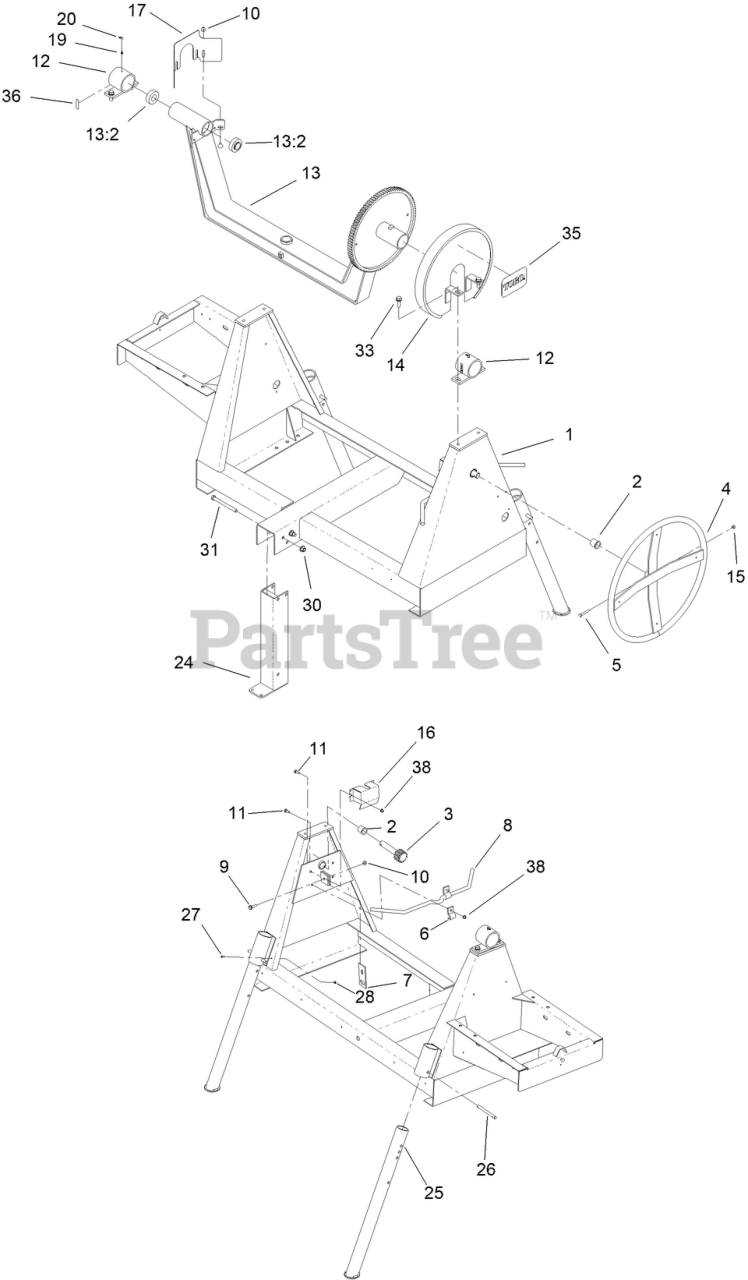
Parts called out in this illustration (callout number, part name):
2	BUSHING-NYLON
3	SHAFT-TILT
4	HANDWHEEL
5	SCREW-HH
6	BRACKET-HANDLE
7	DOG-BRAKE
8	HANDLE-BRAKE
9	SCREW-HHF
10	NUT-HF, NI
11	BOLT-CARR
12	TRUNNION
13	YOKE ASM
13:2	BEARING
14	GUARD-BRAKE, UPPER
15	NUT-LOCK, NI
16	GUARD-BRAKE, LOWER
17	GUARD-PINION
19	FITTING-GREASE
20	CAP-PLUG
24	POST-FOOT
25	LEG-STABILIZER
26	PIN-CLEVIS, LANYARD
27	SCREW-PPH
28	NUT-LOCK, NI
30	NUT-LOCK
31	SCREW-HH
33	SCREW-HWH
35	DECAL
36	DECAL-GREASE
38	NUT-HF, NI
